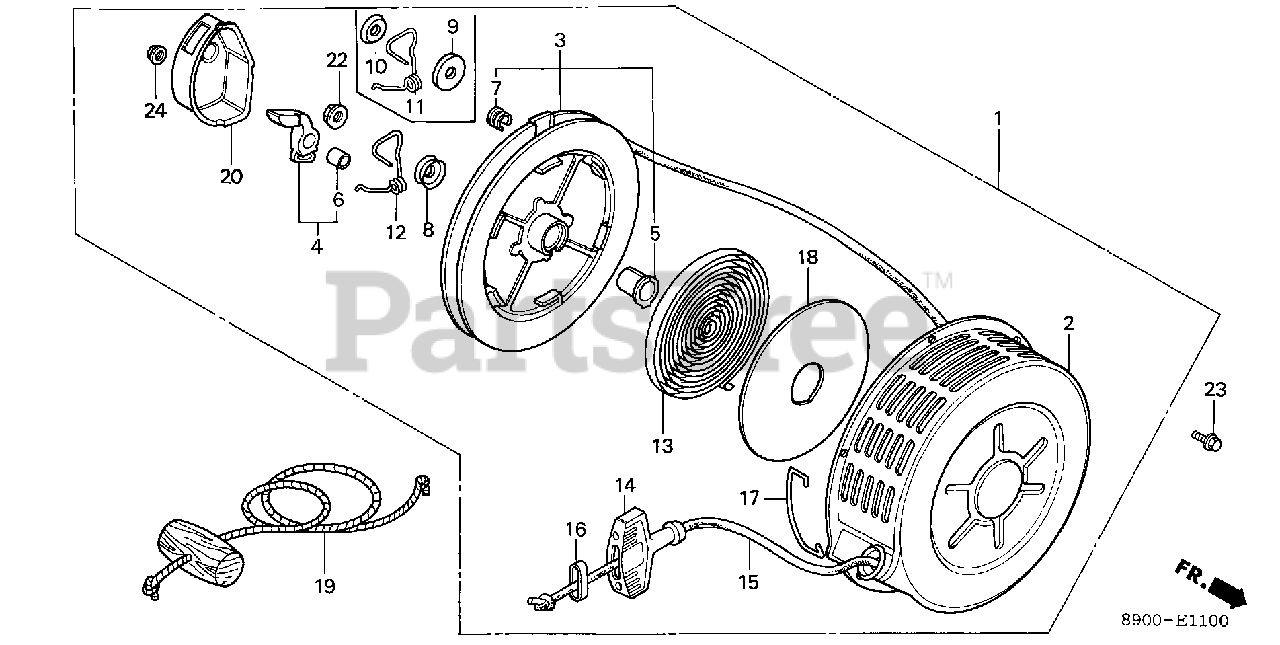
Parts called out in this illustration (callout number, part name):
1	STARTER ASSY., RECOIL *R8* (BRIGHT RED)
2	CASE, STARTER
3	REEL, STARTER
4	RATCHET (NOT AVAILABLE)
5	BOSS, REEL
6	BUSH, RATCHET (NOT AVAILABLE)
7	BUSH, REEL STARTER
9	PLATE A, FRICTION
10	PLATE B, FRICTION
11	SPRING, FRICTION
13	SPRING, RETURN
14	GRIP, STARTER
15	ROPE, STARTER
16	SUPPORT, GRIP
17	HOLDER, ROPE (NOT AVAILABLE)
18	PLATE, SIDE
20	COVER, STARTER REEL
22	NUT, SELF-LOCK (8MM) (CLINCH)
23	BOLT-WASHER (6X10)
24	NUT, FLANGE (6MM)
